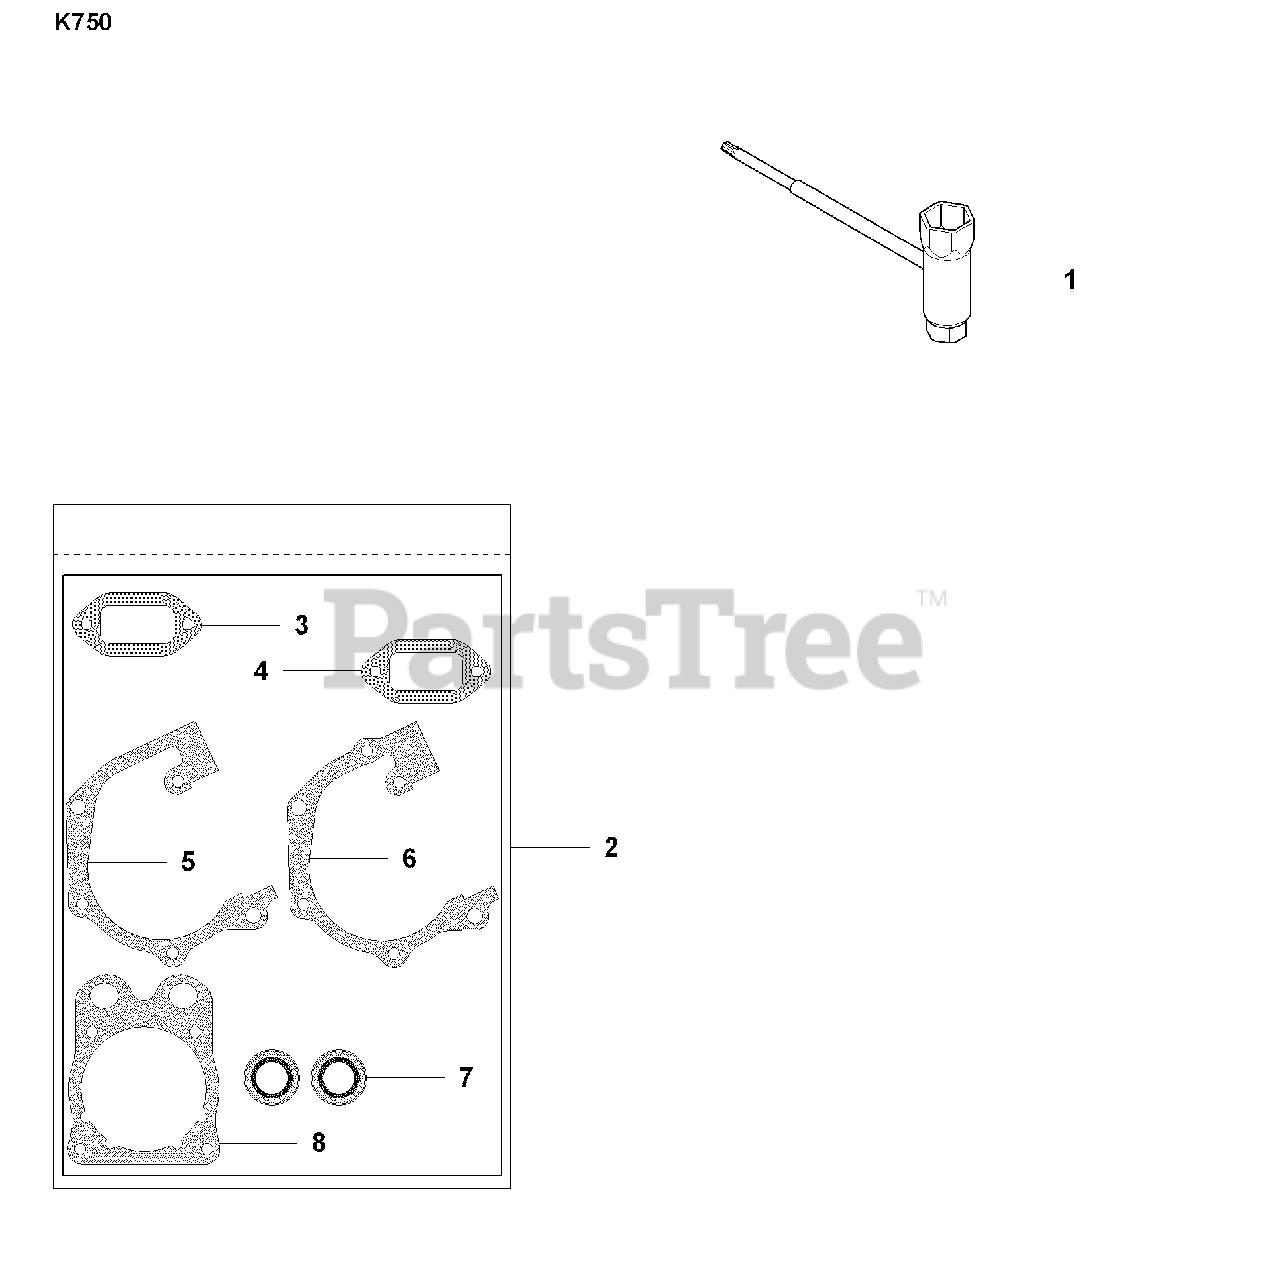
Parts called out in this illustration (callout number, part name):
1	COMBINATION TOOL
2	GASKET KIT
4	GASKET MUFFLER
5	GASKET CRANKCASE
6	GASKET CRANKCASE
7	GASKET CYLINDERBASE
8	SEALING RING
